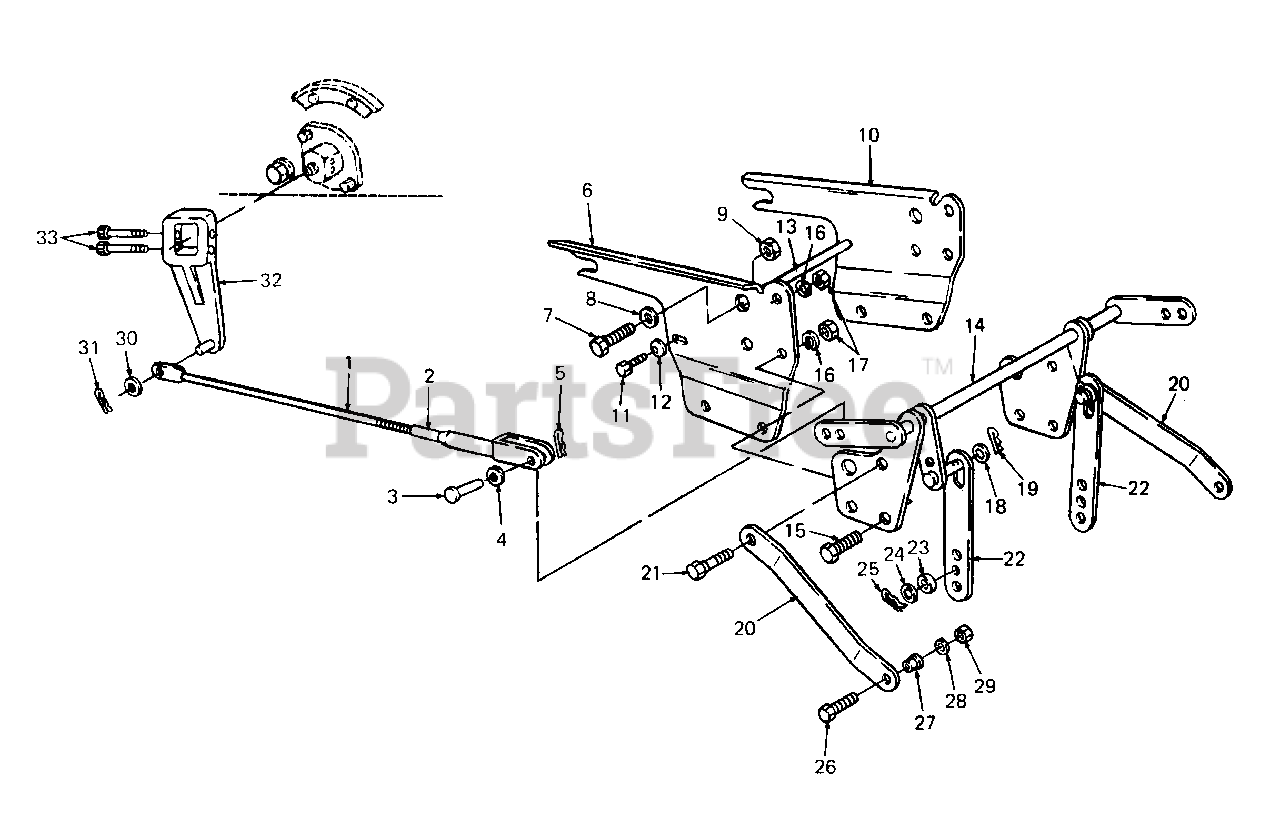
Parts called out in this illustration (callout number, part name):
1	Rod, Lift Handle, .75 Dia X 29.0 Lg
3	Pin, Clevis
4	Washer, Flat, .625 X 1.0 X .067 Thk
5	Pin, Hitch Clip
6	Carriage Brkt - RH
7	Screw, Hex Cap, 1/2-13 X 1.25 Lg GR5
8	Washer, Belleville, .505 X 1.0 X .075 Thk
9	Nut, Pilot Weld, 1/2-13
10	Carriage Brkt - LH
11	Screw, Hex Cap, 5/16-24 X 1.0 Lg
12	Washer, Belleville,.345 X .88 X .060 Thk
13	Rod, Carriage Brkt, Support
14	Pivot Assy
15	Screw, Hex Cap, 1/2-20 X 1.25 Lg
16	Washer, Lock, 1/2
17	Nut, Hex Jam, 1/2-20
18	Washer, Flat, .625 X 1.0 X .067 Thk
19	Pin, Hitch Clip
20	Pivot Link, 15.5 Lg
21	Bolt, Shoulder, .625 Dia X .36 Lg
22	Lift Link, 12.91 Lg
23	Spacer, .635 X .885 X .33 Lg
24	Washer, Flat, .625 X 1.0 X .067 Thk
25	Pin, Hitch Clip
26	Screw, Hex Cap, 3/8-24 X 1.25 Lg GR5
27	Spacer, Shoulder, .38 ID
28	Washer, Lock, 3/8
29	Nut, Hex Insert Lock, 3/8-24
30	Washer, Flat, .510 X 1.0 X .060 Thk
31	Pin, Internal Cotter
32	Arm, Lift
33	Screw, Socket Hd
